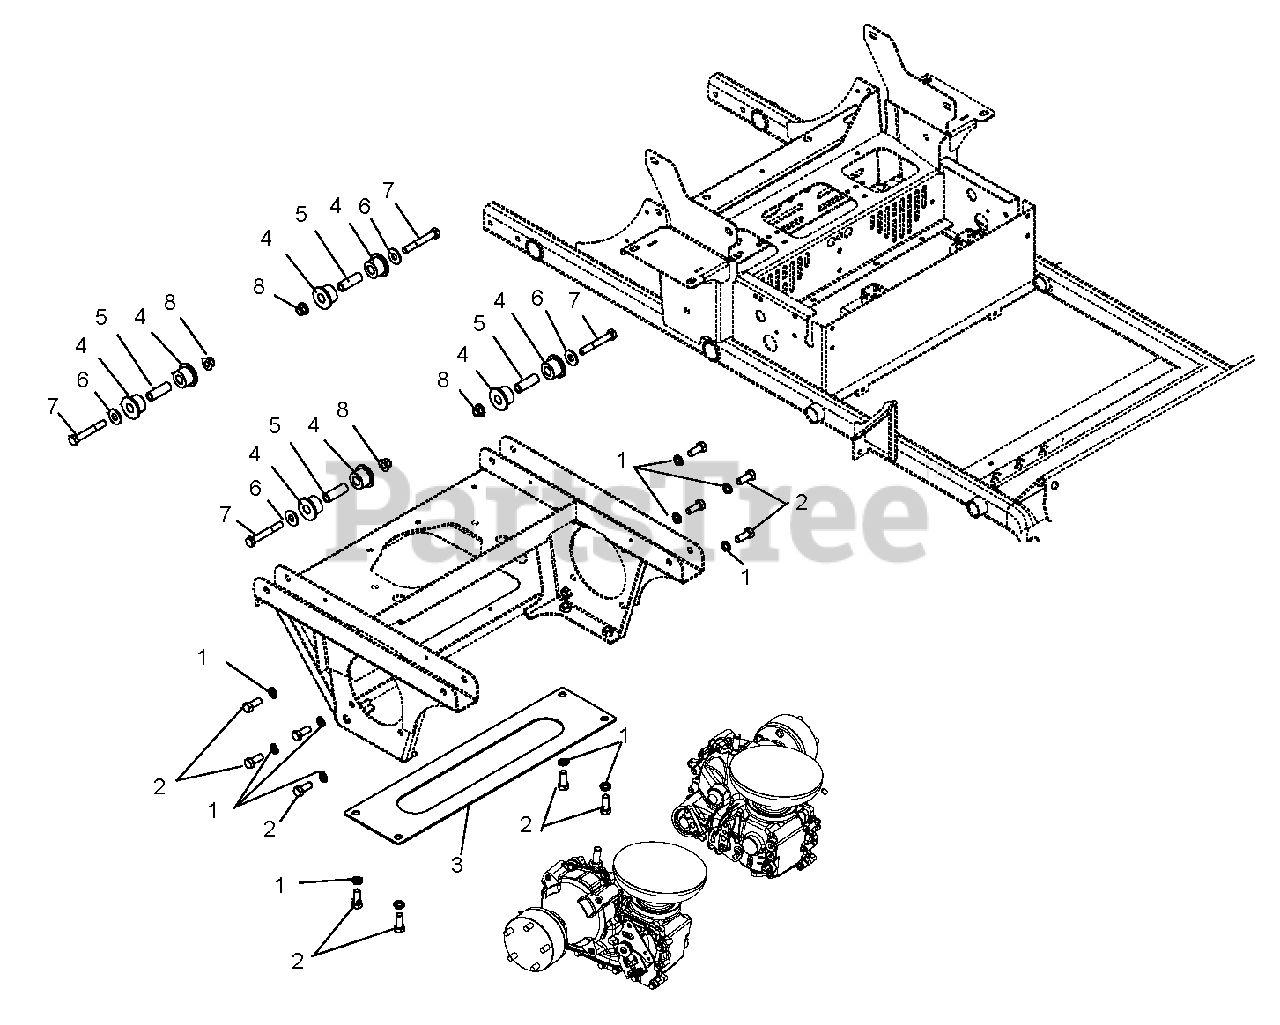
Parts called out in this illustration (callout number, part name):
1	Washer, Lock .50 x .125 REG YWZC
2	Bolt, Hex .50-13 x 1.25 GR5 YWZC
3	Plate, Transmission Connecting
4	Bushing, Flange .75 x 1.51 x 1.13 x 2.0 URE
5	Bushing, Sleave .50 x .75 x 2.23
6	Washer, Flat Steel .563 x 1.38 x .109 YWZC
7	Bolt, Hex .50-13 x 3.50 GR5 YWZC
8	Nut, Locking Nylon Flange .50-13 YWZC
